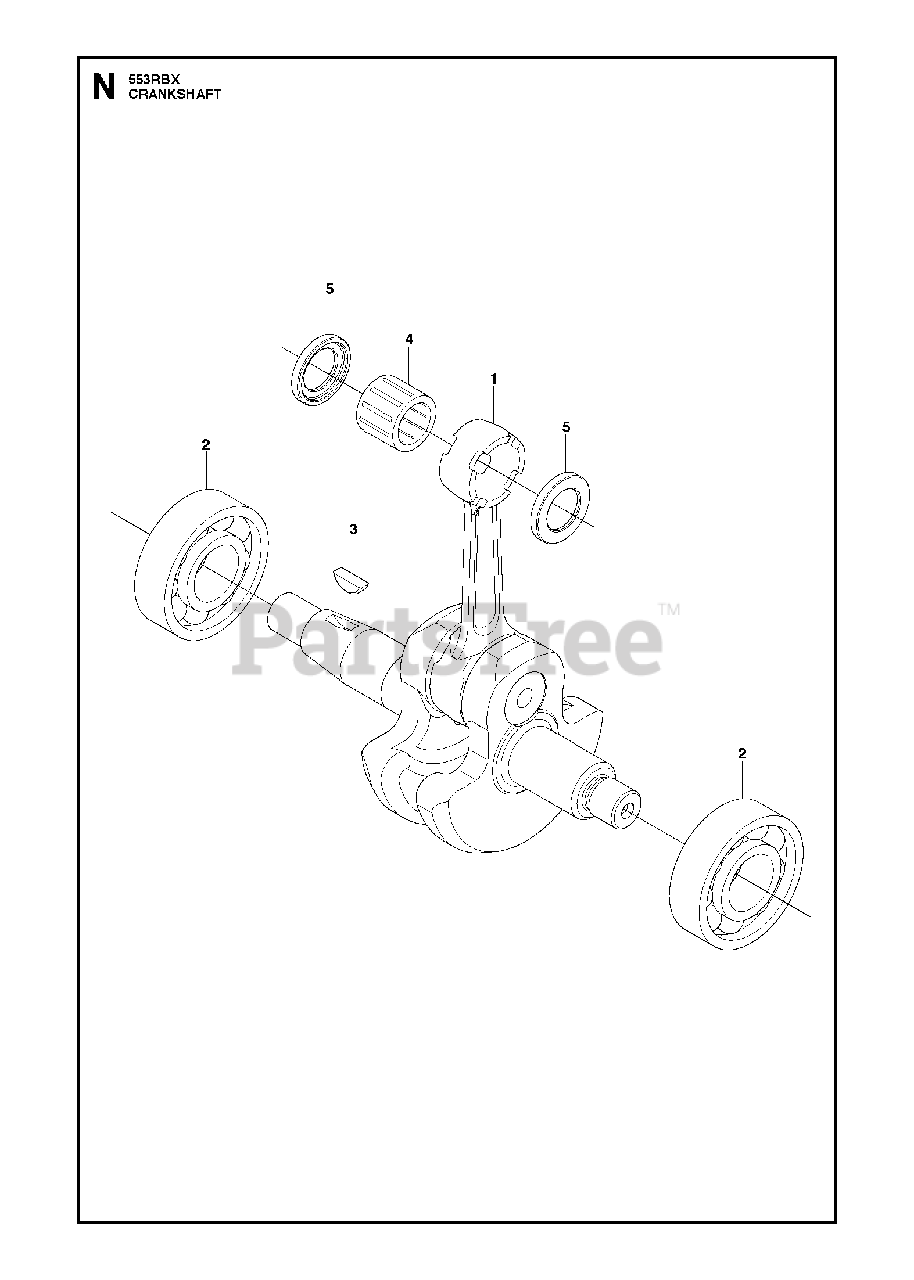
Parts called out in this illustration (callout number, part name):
1	CRANKSHAFT COMP
4	BEARING (RPLS 335041410)
5	WASHER, THRUST
